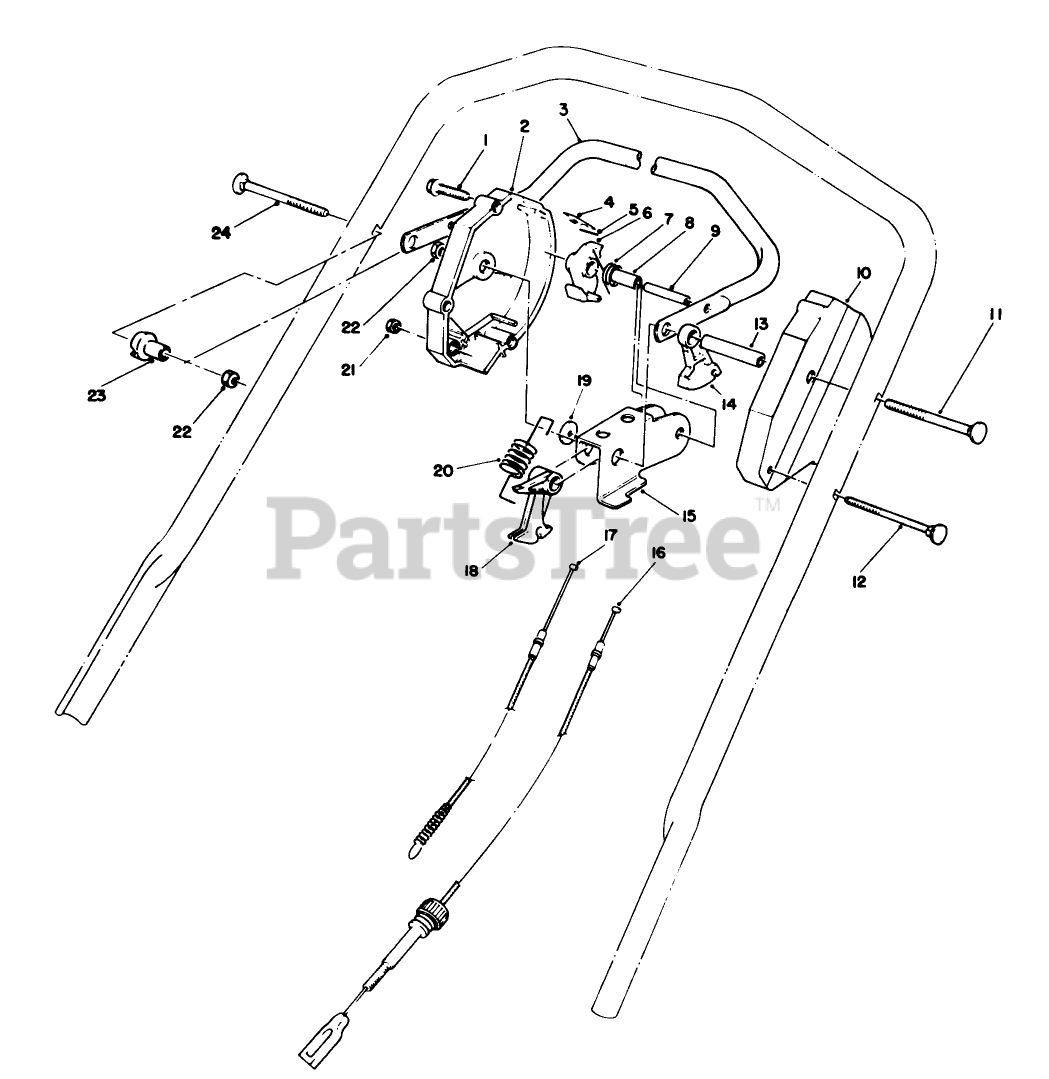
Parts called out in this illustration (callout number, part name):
1	SCREW-HWHTF
4	SPRING-LEAF
5	PIN-INSERT
6	HOOK-CONTROL
7	SPRING-TORSION
8	SPACER
9	PIN-ROLL, SLOTTED
12	HANDLE SCREW
13	TUBING-SPACER
14	LEVER-TRACTION
16	TRACTION CABLE
17	CLUTCH CABLE
18	LEVER-CABLE
19	WASHER-NYLON
20	SPRING-DETENT
21	NUT-HEX
22	NUT-LOCK, NI
23	SPACER-SUPPORT
